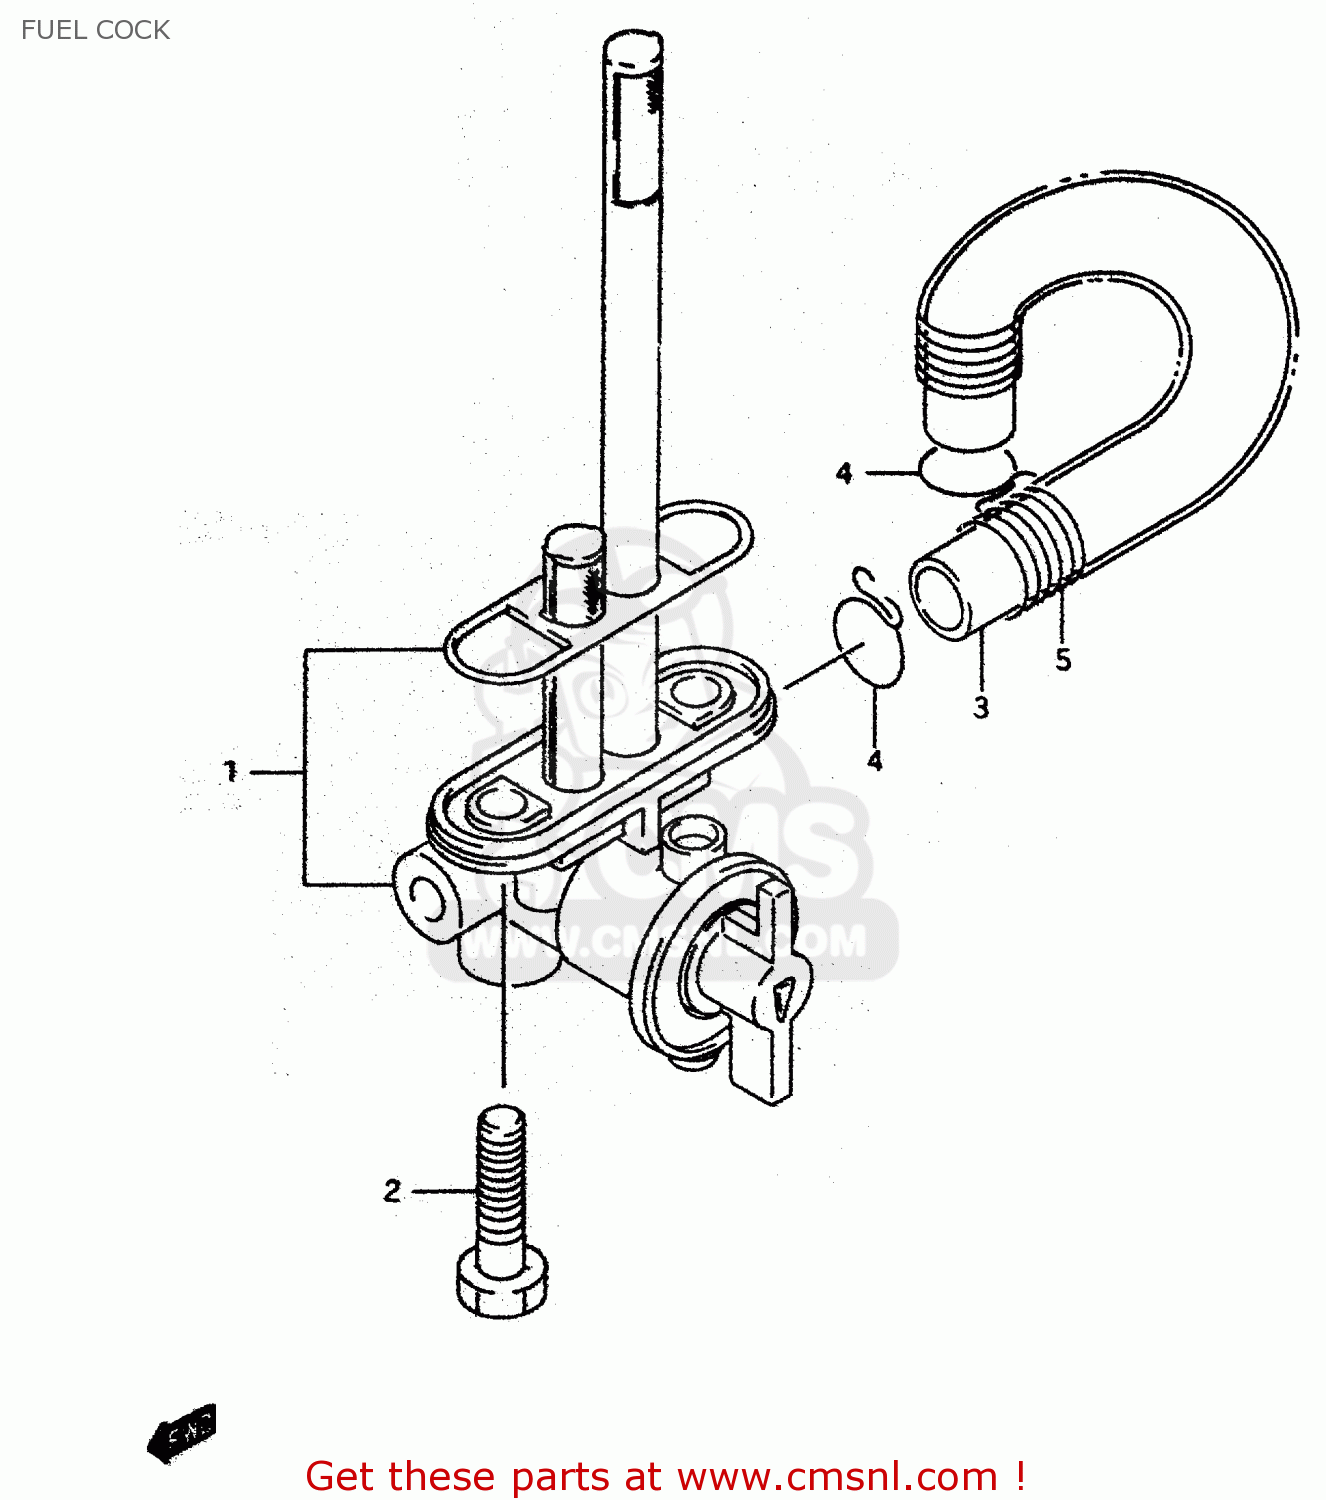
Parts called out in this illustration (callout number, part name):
1	COCK ASSY,FUEL
2	SCREW
3	HOSE(7X10.2X600)
4	CLIP
5	SPRING
